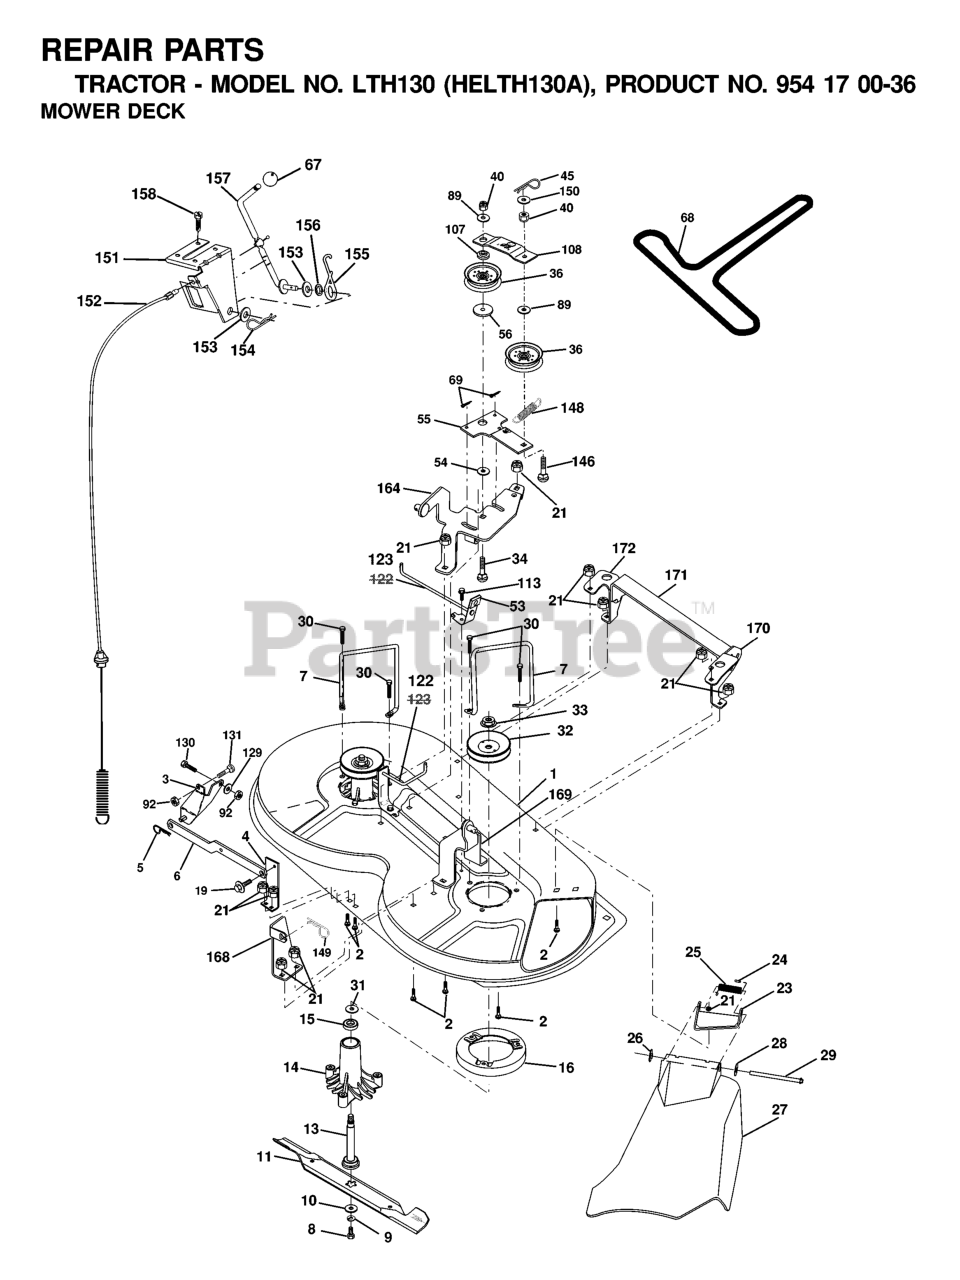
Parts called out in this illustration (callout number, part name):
2	RP BOLT 5/16-18 X3/4 ZN/YEL GR
3	BRKT ASM SWAY BAR
5	RETAINER-SPRNG RB
6	REAR SUSP ARM
8	BLADE BOLT
9	LOCKWASHER
10	WASHER.BLADE
11	BLADE, HI-LIFT 36" PREMIUM
13	SHAFT ASM VENT
14	HOUSING.MANDREL.VENTED (MACHD)
16	STRIPPER
19	BOLT SHD 5/16-18
21	LOCKNUT
23	BRACKET ASM DEFLECTOR
24	CAP-SLEEVE LT
25	SPRING TORSION
26	NUT PUSH M
27	CONSOLE.STLT.5SP.BLK
28	Washer 11/32 x 5/8 x 16 Ga SD
29	HINGE ROD
30	SCREW THDROL ROLLING WASHER HD
31	WASHER
32	PULLEY, MANDREL
33	NUT
36	FLAT IDLER PULLEY
45	RETAINER M
53	BRAKE ASSEMBLY
54	HARDENED WASHER
56	SPACER.RETAINER.MOWER
67	KNOB T (3/8 HOLE)
69	COTTER PIN
89	WASHER GT
92	NUT
107	SPACER.IDLER.ARM
108	STIFFENER.IDLER.ARM
113	Screw 5/16-18 x 1/2 Hex, Self Tapping 5/16-18 x 1/2
129	WASHER
131	BOLT D
146	BOLT, CARRIAGE IDLER
148	IDLER RETURN SPRING
149	SPRING.RETAINER.YELLOW.ZINC
151	BRACKET.CLUTCH.CABLE
153	WASHER FLAT 3/8"
154	SPRING RETAINER
155	SPRING RETENTION LEVER
156	SPACER.CLUTCH.CABLE
157	ROD CLUTCH CABLE 3/8"
158	SCREW LT
171	BRACE.SUPT.SUSP.FRT.CRD
